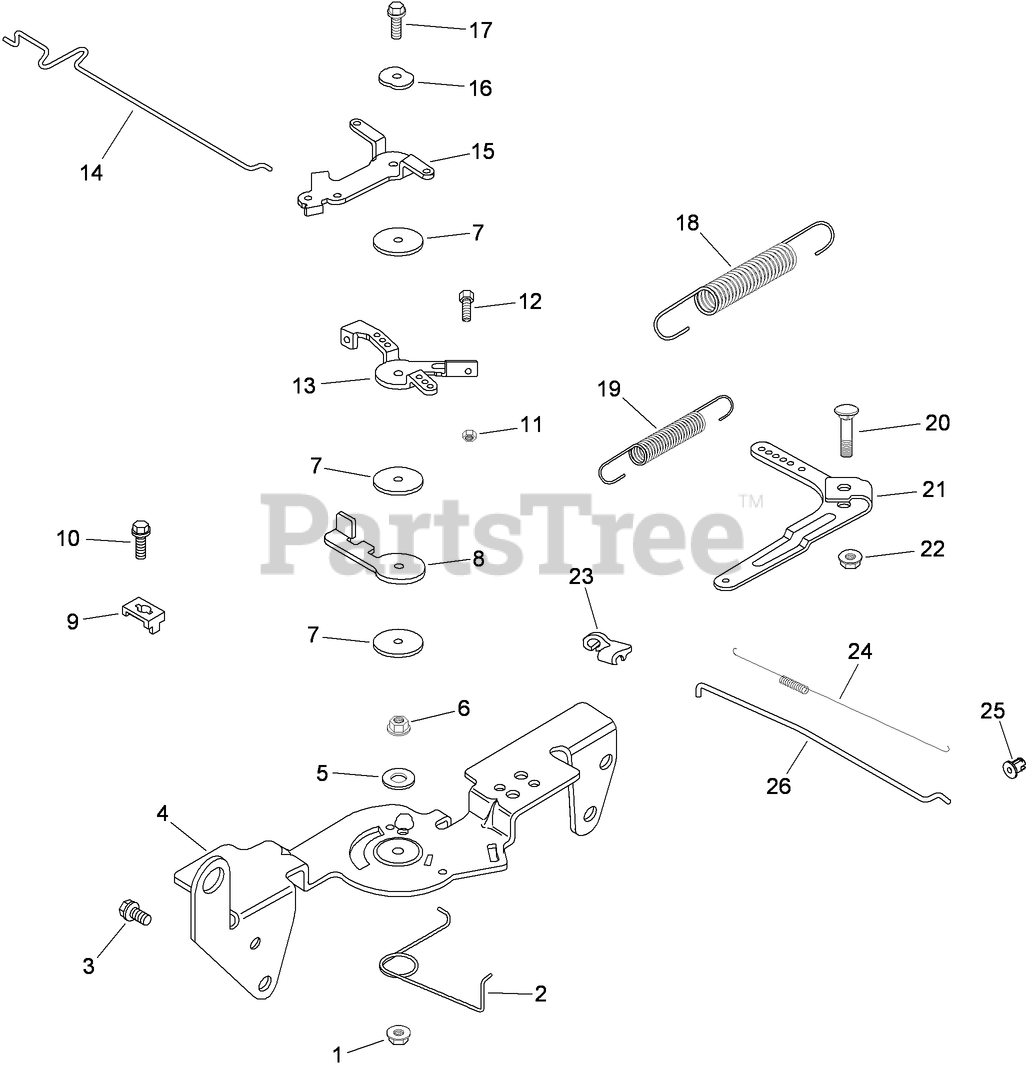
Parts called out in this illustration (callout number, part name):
1	NUT-LOCK (M5X.8)
2	SPRING-RETURN, CHOKE
3	SCREW-FLANGE, THREAD FORMING (M6X1.0X16)
4	Bracket-Control
5	Washer-Lock (.25)
6	Nut-HF (M5x0.8)
7	WASHER-FLAT (5.5MM)
8	Lever-Actuator, Throttle
9	CLAMP-CABLE
10	SCREW-FLANGE, THREAD FORMING (M5X0.8X16)
11	NUT (M4X0.7)
12	Screw (M4x0.7x30)
13	Lever-Control, Throttle
14	Linkage-Choke
15	LEVER-CHOKE
16	WASHER-SPRING (1/4)
17	SCREW-FLANGE, THREAD FORMING (M5X.8X20)
18	Spring-Limiter, Throttle
19	Spring-Governor
20	BOLT-SQ NECK, RD HD (M6X1.0X25)
21	Lever-Governor
22	NUT-FLANGE (M6X1.0)
23	BUSHING-RETAINING, LINKAGE
24	SPRING-LINKAGE
25	BUSHING-LINKAGE, THROTTLE
26	Linkage-Throttle
